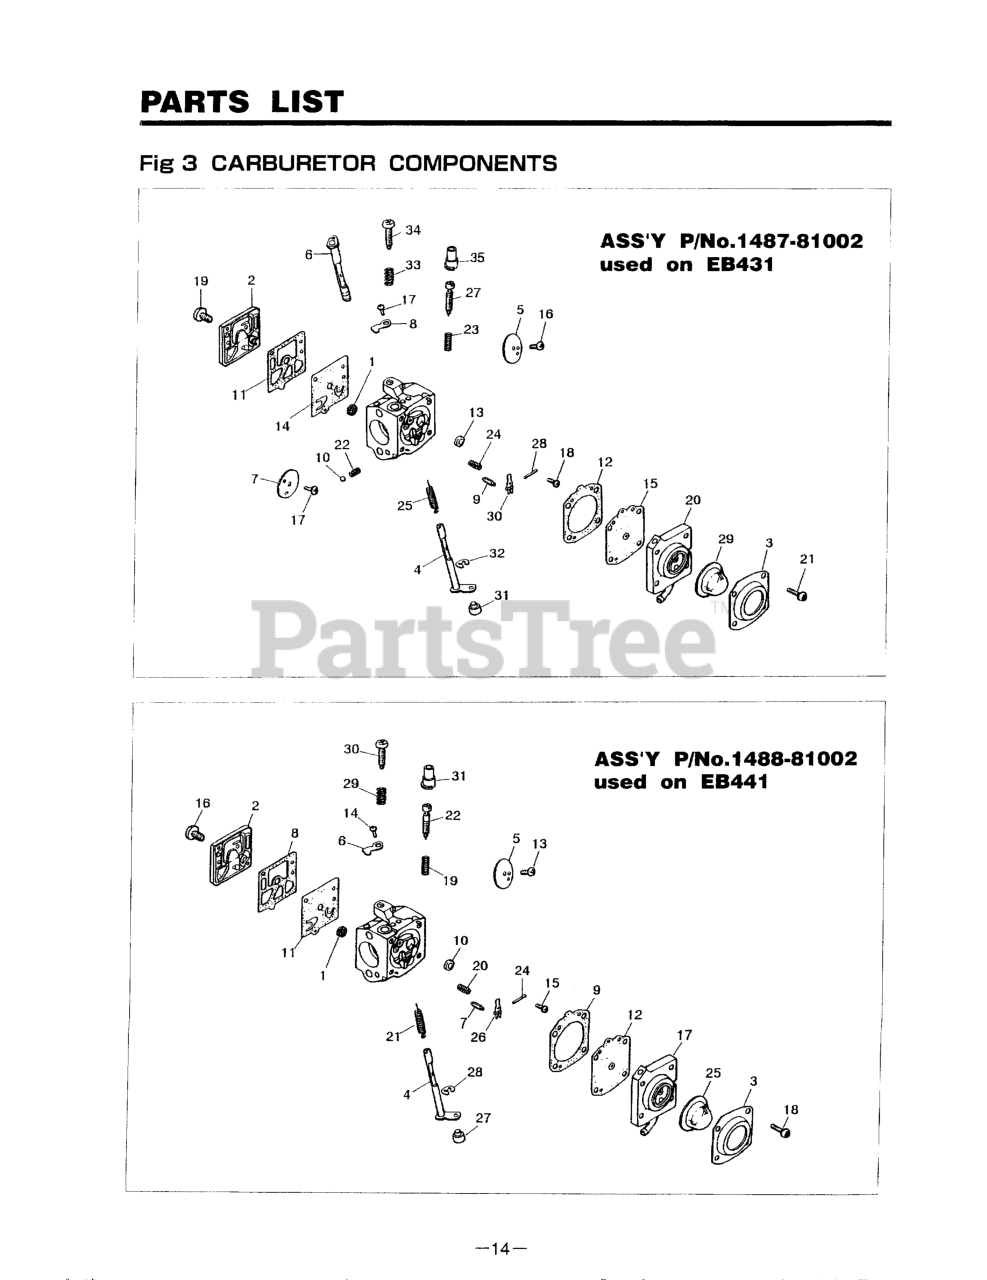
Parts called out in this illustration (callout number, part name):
2	COVER, PUMP
3	COVER, PUMP
4	SHAFT ASSEMBLY
6	SHAFT ASSEMBLY
7	VALVE, CHOKE
8	THROTTLE STOP
9	VALVE, INLET
10	BALL, FRICTION
11	KIT ONLY
12	KIT ONLY
13	PLUG, WELSH
14	KIT ONLY
20	BODY ASSY (RPLS 1491-81490)
21	SCREW (REPLACES 1491-81350)
22	SPRING
24	KIT ONLY
25	SPRING
27	NEEDLE (NLA)
28	PIN, METERING LEVER
29	PUMP, PRIMER
30	KIT ONLY
31	SWIVEL (USE -06040)
33	SPRING, IDLE
NI	CARBURETOR (RPLS-81001)
